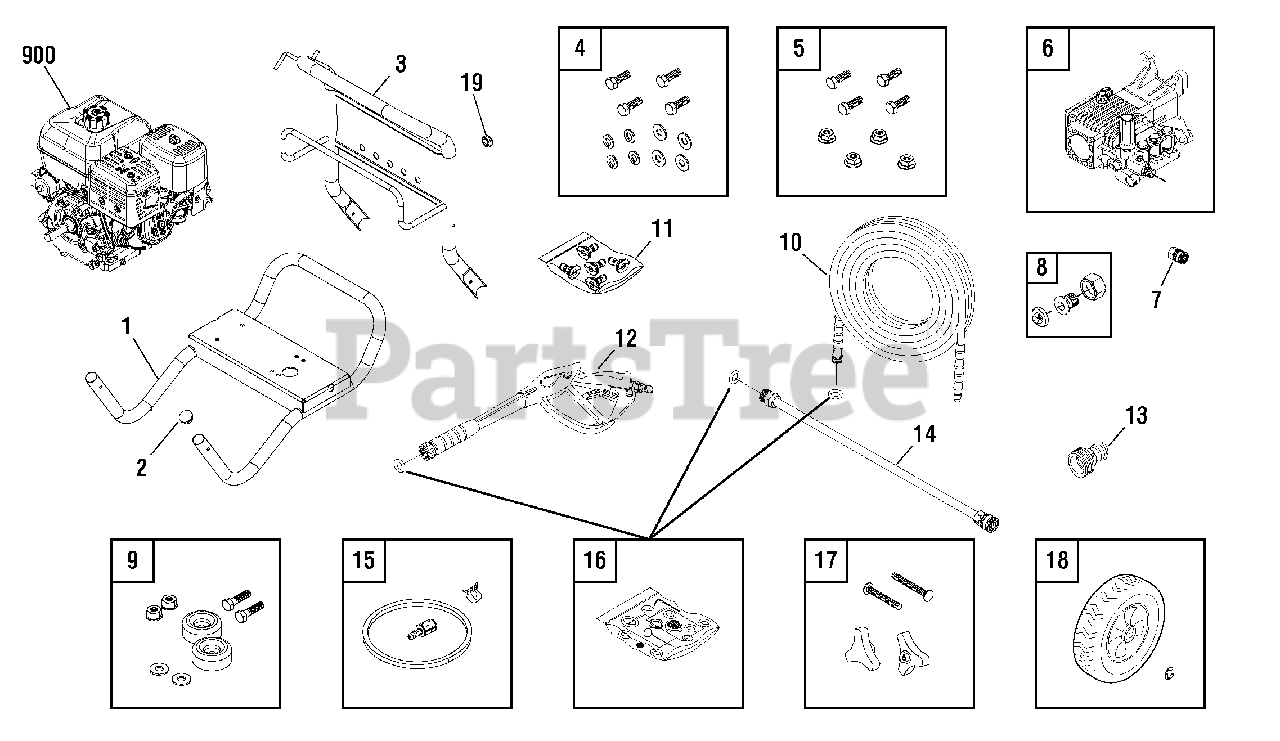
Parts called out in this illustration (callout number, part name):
4	KIT-HARDWARE, PUMP MOUNTING
5	KIT-HARDWARE, ENGINE MOUNTING
7	QUICK CONNECT
8	ADAPTER-GARDEN HOSE
9	MOUNT-VIBRATION
10	HOSE
12	GUN
14	EXTENSION, QC
16	KIT-O-RING
17	KIT-HARDWARE, HANDLE
900	** ENGINE
